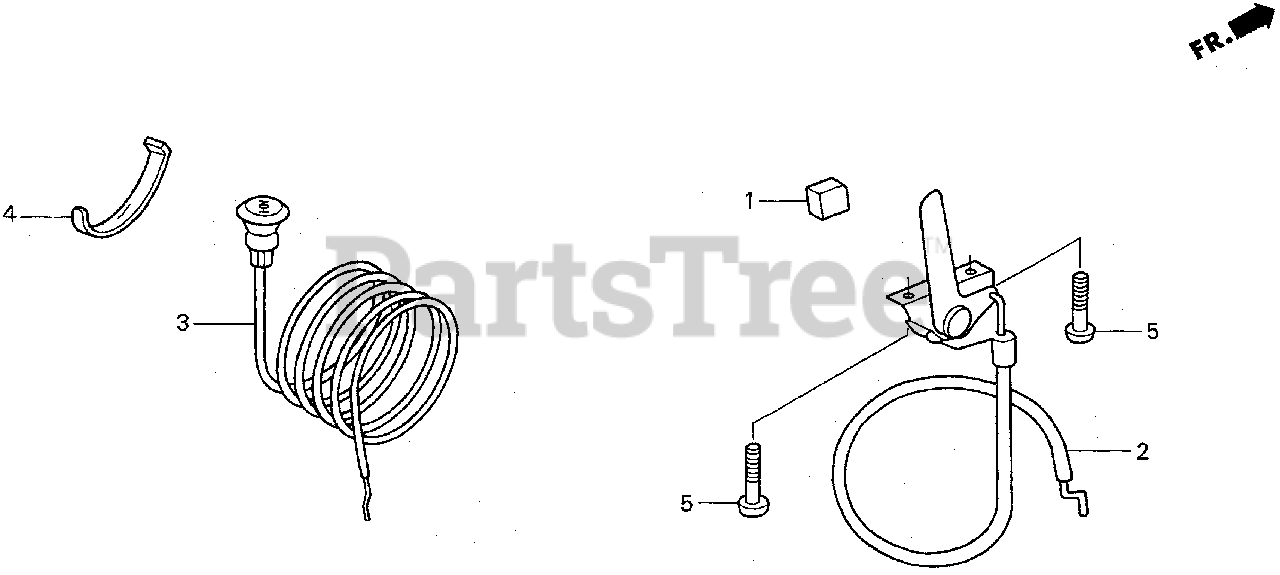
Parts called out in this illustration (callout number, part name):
1	KNOB, THROTTLE LEVER
2	CABLE, THROTTLE
3	CABLE, CHOKE
4	TIE, CABLE
5	SCREW A, TAPPING
